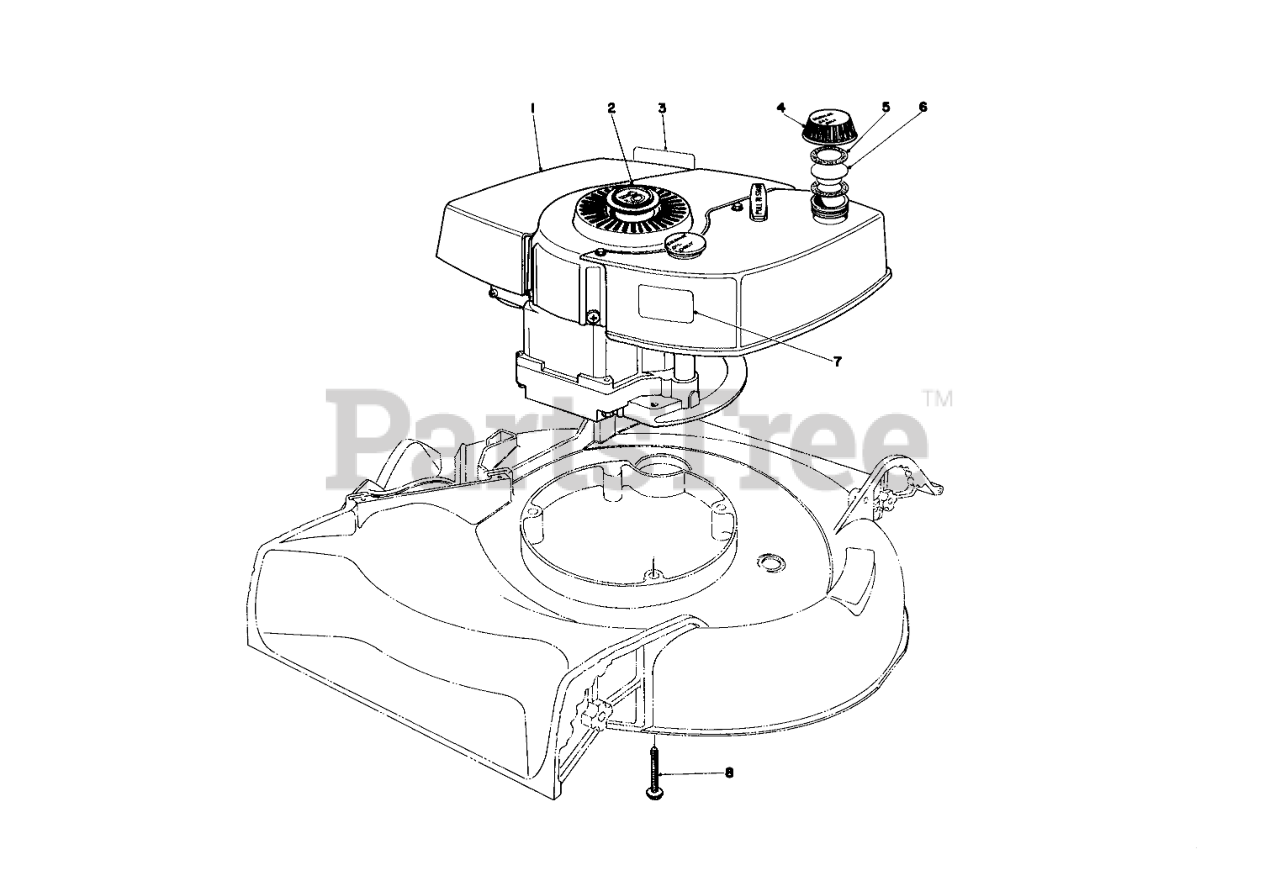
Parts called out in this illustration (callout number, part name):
1	Engine
2	Plug Button
3	Decal Maintenance
4	Gas Cap (Incl. Ref. #5 & 6)
5	GASKET
6	GAS CAP BAFFLE
7	Decal Engine
8	3/8-16 X 2-3/4 CAPSCR
